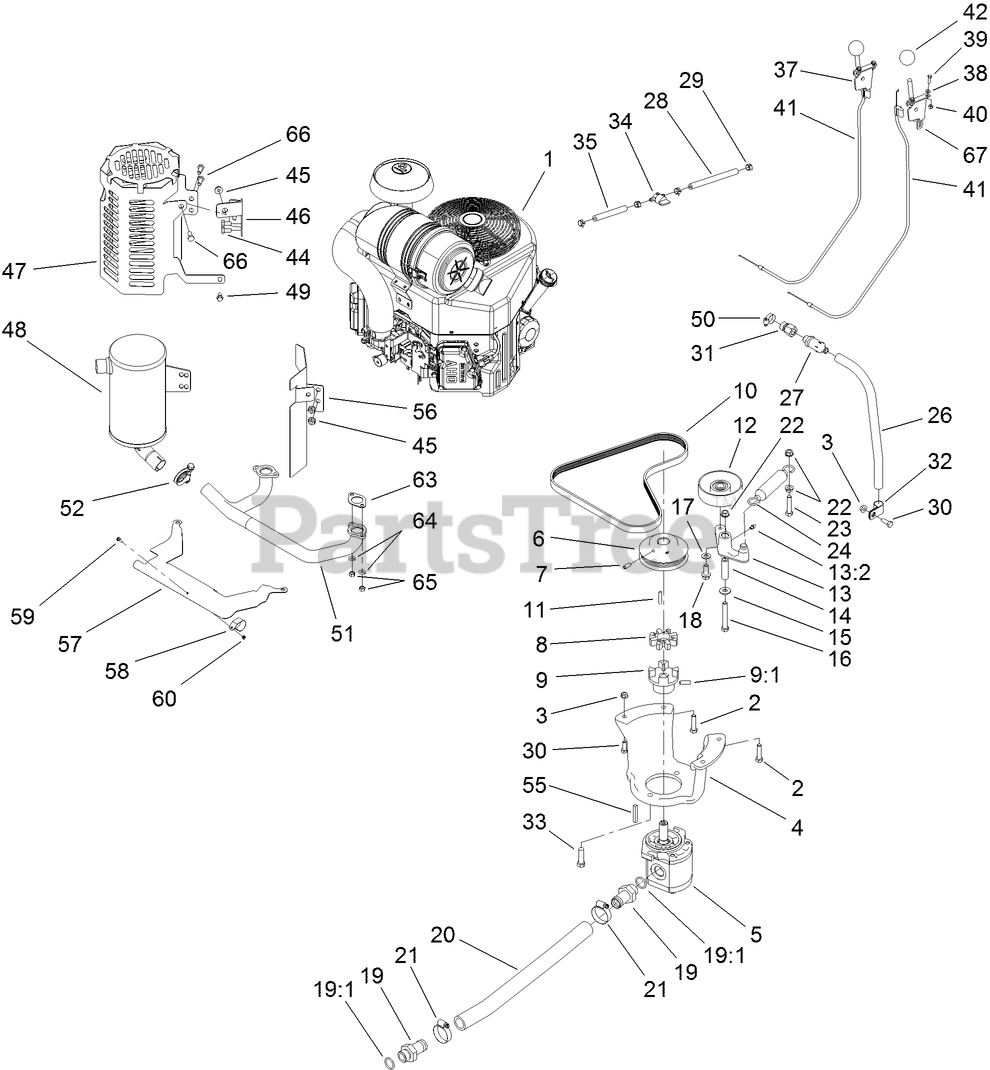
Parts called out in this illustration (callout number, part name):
1	ENGINE-KAWASAKI, FX730V
2	SCREW-HH
3	NUT-HF
4	MOUNT-PUMP
5	GEAR PUMP ASM
6	PULLEY-ENGINE
7	SCREW-SET, HSH
8	COUPLER-SPIDER
9	COUPLER-FLEX
9:1	SCREW-SET
10	BELT-V
11	KEY-SQUARE
12	PULLEY-IDLER
13	IDLER ARM ASM
13:2	FITTING-GREASE
14	BUSHING-IDLER
15	WASHER-FLAT
16	SCREW-HH
17	WASHER-FLAT
18	SCREW-HHF
19	FITTING
19:1	O-RING
20	HOSE-SUCTION
22	NUT-HHF, WHIZ
23	SCREW-HH
24	Spring-Extension
26	HOSE-VENT
27	VALVE-DRAIN, OIL
28	HOSE-FUEL
29	CLAMP-HOSE
30	SCREW-HH
31	Adapter
32	CLAMP-R
33	SCREW-HH
34	VALVE-FUEL
35	HOSE-FUEL
37	LEVER-CONTROL
38	WASHER-FLAT
40	NUT-LOCK, NI
41	CABLE-CONTROL
44	SCREW-HH
45	NUT-HF
46	BRACKET-MOUNT, MUFFLER
47	SHIELD-MUFFLER
48	MUFFLER
49	SCREW-HHF
50	CLAMP-HOSE
51	MANIFOLD
52	CLAMP-MUFFLER
55	KEY-SQUARE
56	BRACKET-SHIELD, HEAT
57	PLATE-SHIELD, HEAT
59	SCREW-PAN
60	NUT-HEX
63	GASKET-EXHAUST
64	WASHER-SPRING
65	NUT-HEX
66	SCREW-HH
67	LEVER-CONTROL
